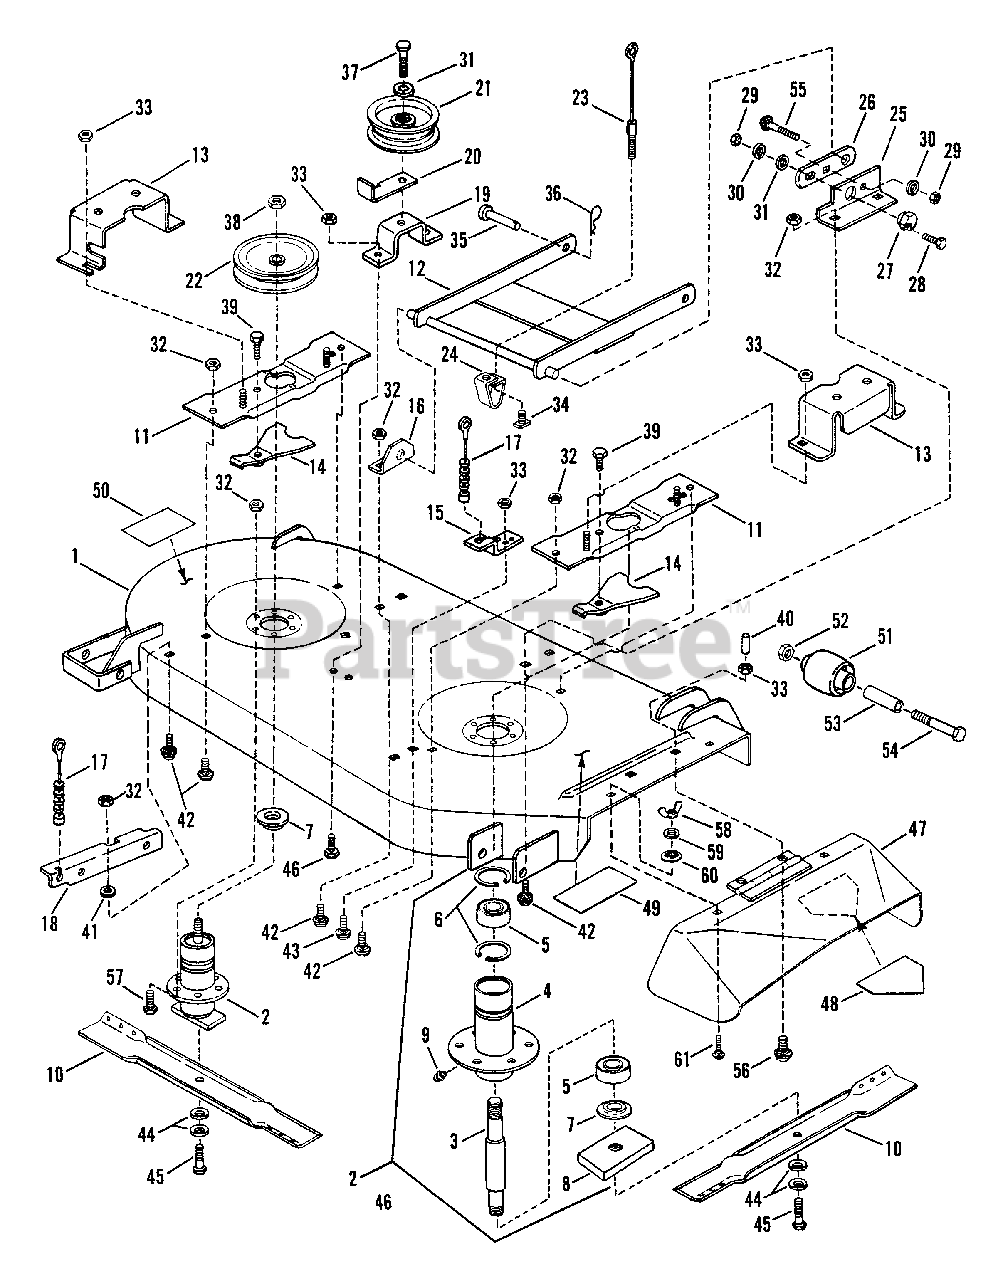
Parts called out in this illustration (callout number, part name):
1	DECK, Mower, 41"
2	ASSEMBLY, Spindle
3	SPINDLE 6.5"
4	HOUSING, Spindle
5	BEARING, Spindle
6	RING, Retaining
7	WASHER, Spindle
8	HOLDER, Blade
9	FITTING, Lube (Press fit for .187 hole-no ball)
10	BLADE, 21" Cutter
11	ASSEMBLY, Rear Support
12	ASSEMBLY, Front Hanger
13	GUARD, Pulley
14	ASSEMBLY, Spindle Lock
15	ASSEMBLY, Chain Support
16	BRACKET, Front Left Hanger
17	CABLE, Support 4.25", 8 Spacers
18	ASSEMBLY, Rear Support
19	BRACKET, Idler Mount
20	GUIDE, Belt
21	PULLEY, Idler
22	PULLEY, Spindle
23	CABLE, Front Lift 6.12"
24	BRACKET, Front Lift Arm Hanger
25	BRACKET, Front Right
26	LINK, Adjustment
27	RING, Adjustment
28	SCREW, 3/8-16 x 1" Hex Head Cap
29	NUT, 3/8-16 Hex
30	WASHER, 3/8" Split Lock
31	WASHER, 3/8" Flat
32	NUT, 3/8-16 Hex Flange Lock
33	NUT, 5/16-18 Hex Flange Lock
34	T-NUT, 5/16-18
35	PIN, 1/2 x 1 3/8" Clevis
36	HAIRPIN, Cotter
37	SCREW, 3/8-16 x 1 1/2" Hex Cap
38	NUT, 3/4-16 Hex Jam
39	BOLT, 3/8-16 x 1" Hex Flange Lock
40	CAP, Vinyl
41	WASHER, 7/16 Flat
42	BOLT, 3/8-16 x 3/4" Carriage
43	BOLT, 5/16-18 x 3/4" Carriage
44	WASHER, 13/32 x 1 13/32" Dia., Cone
45	SCREW, 3/8-24 x 1 1/4" Hex Cap
46	BOLT, 5/16-18 x 3/4" Hex Flange Lock
47	DEFLECTOR, Side Chute
48	DECAL, Danger
49	DECAL, Caution (Deflector in Place)
50	DECAL, Caution (Rotating Blades)
51	WHEEL, Gage
52	LOCKNUT, 3/8-24 Hex
53	SPACER
54	SCREW, 3/8-24 x 3 3/4" Hex Head Cap
55	BOLT, 3/8-16 x 3/4" Short Neck Carriage
56	BOLT, 5/16-18 x 1" Short Neck Carriage
57	BOLT, 3/8-16 x 3/4" Hex Flange Lock
58	WING-NUT, 5/16-18
59	WASHER, 5/16 Split Lock
60	RETAINER, 5/16 Bolt
61	BOLT, 5/16-18 x 5/8" Carriage
